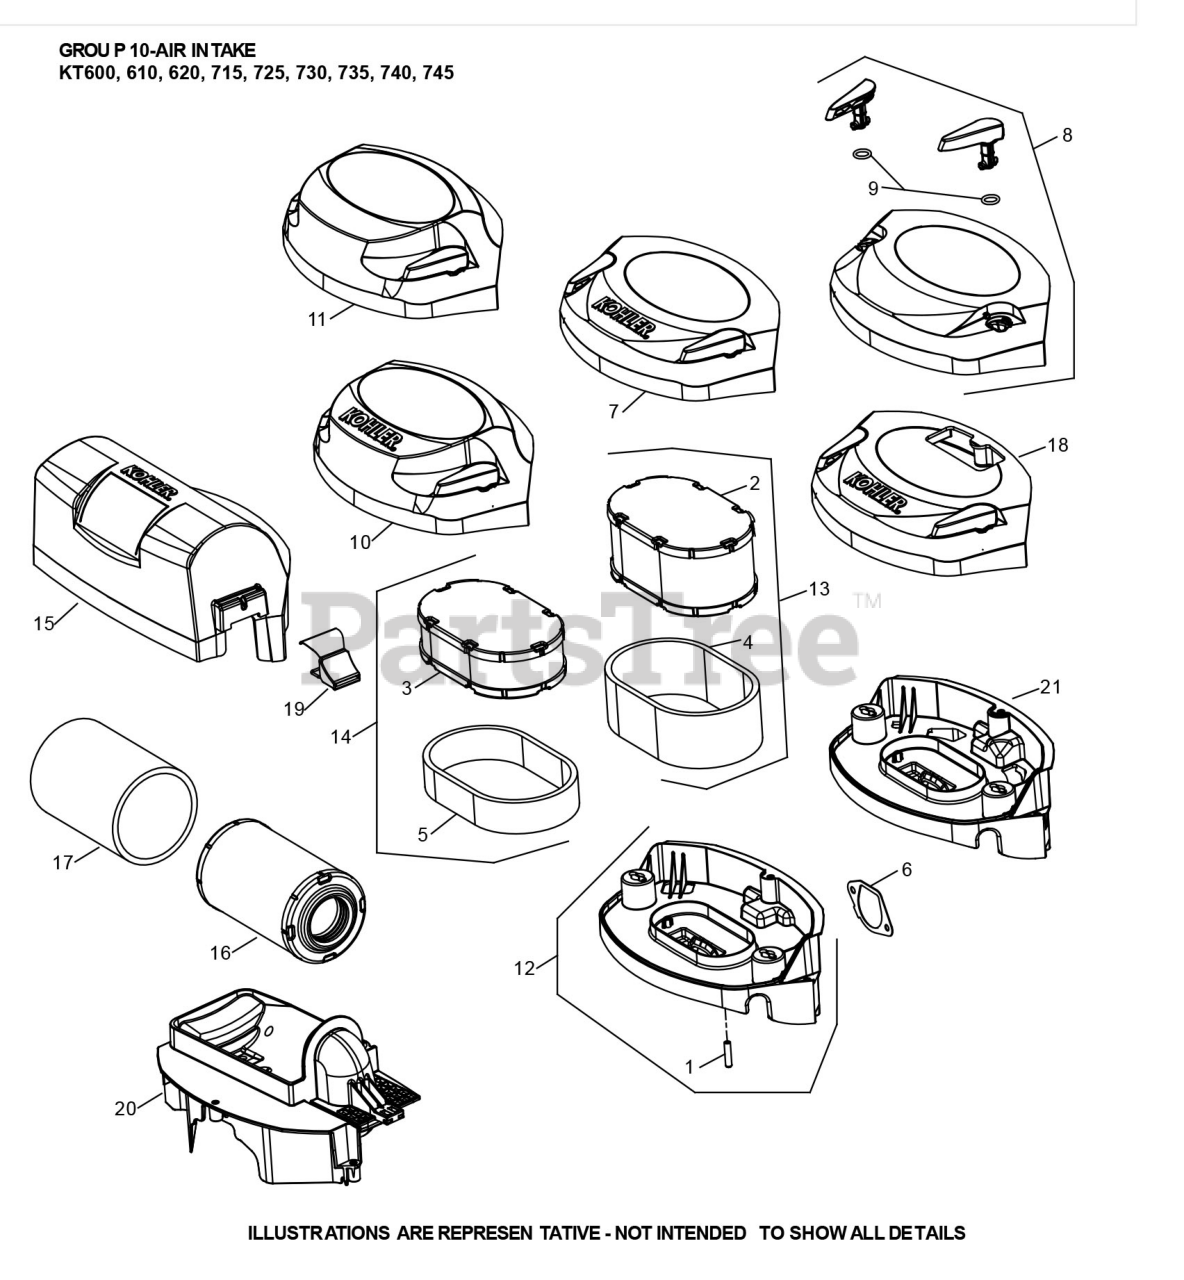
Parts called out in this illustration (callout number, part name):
6	GASKET-AIR CLNR BA
15	COVER, AIR CLEANER
16	AIR FILTER/PRECLEANER KIT
17	ELEMENT, PRE-CLEANER
19	AIR CLEANER COVER
20	AIR CLEANER BASE
